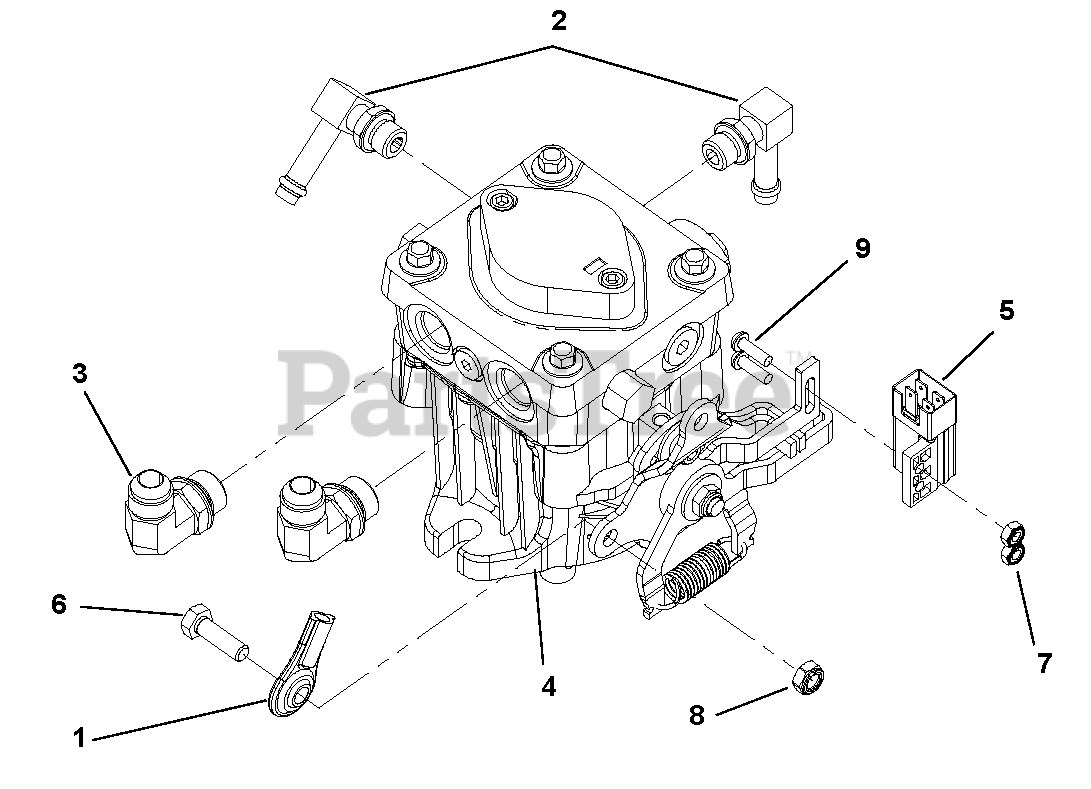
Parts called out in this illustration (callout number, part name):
1	Alignaball, 5/16 RH/Thread
2	Fitting, 90 9/16MOR x 3/8 Hose
3	Fitting
4	Pump, Hydraulic LH
5	Switch, Plunger Diametral Pitch -N.O. -N.C.
6	Bolt, Hex 5/16-18 x 1.00 Grade 5
7	Nut, Locking, Nylon 10-24 w/Insert
8	Nut, Locking, Nylon .312-18
9	Screw, Machine 10-24 x .62 P/HD
NS	Pump Seal Kit
